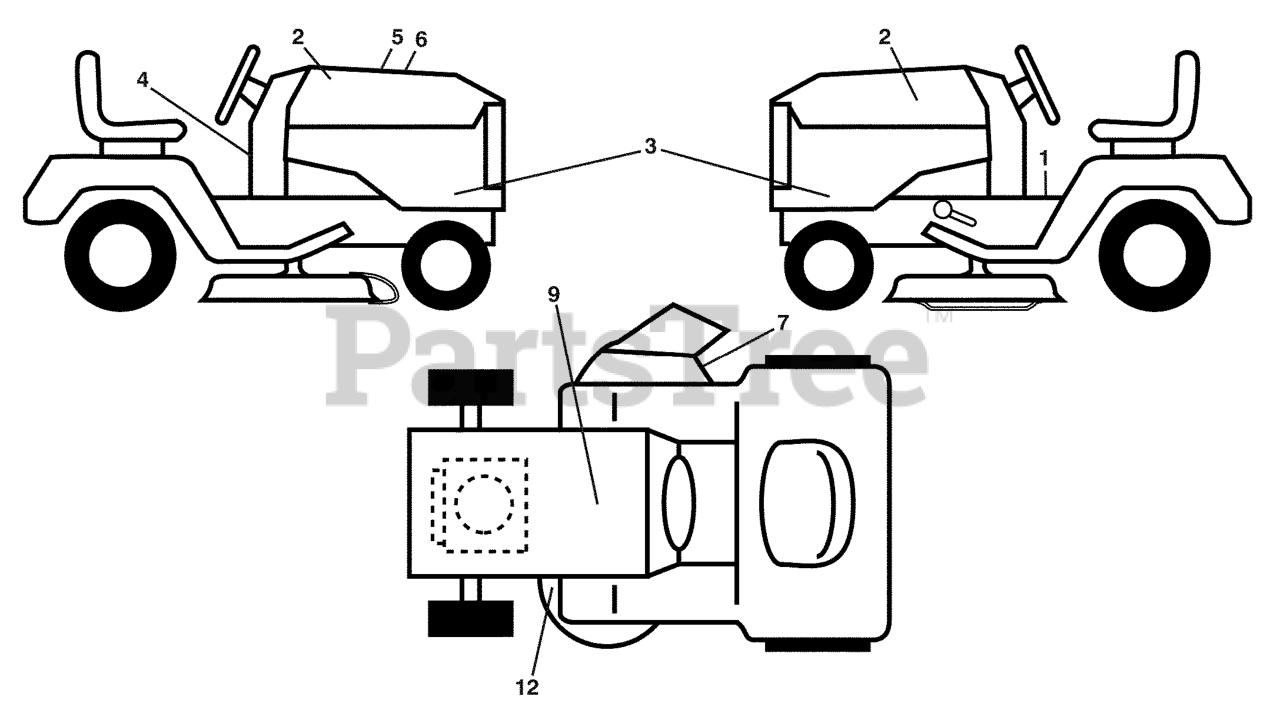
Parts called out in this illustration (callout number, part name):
1	DECAL.FENDER.WARNING.ENG
2	RP EMBLEM, HOOD
3	DECAL.PNL.SD.YTH21K46.HUSQ.KOH
4	DECAL, WARNING SPARK ARRESTOR
5	DECAL.WARNING.CUST.RESP.E85.
6	DECAL.REPLACEMENT.96043008500
7	DECAL.WARN.KEEP.HAND.AWAY
9	DECAL BTRY SYMBOLS
12	DECAL V BELT SCHEMATIC
